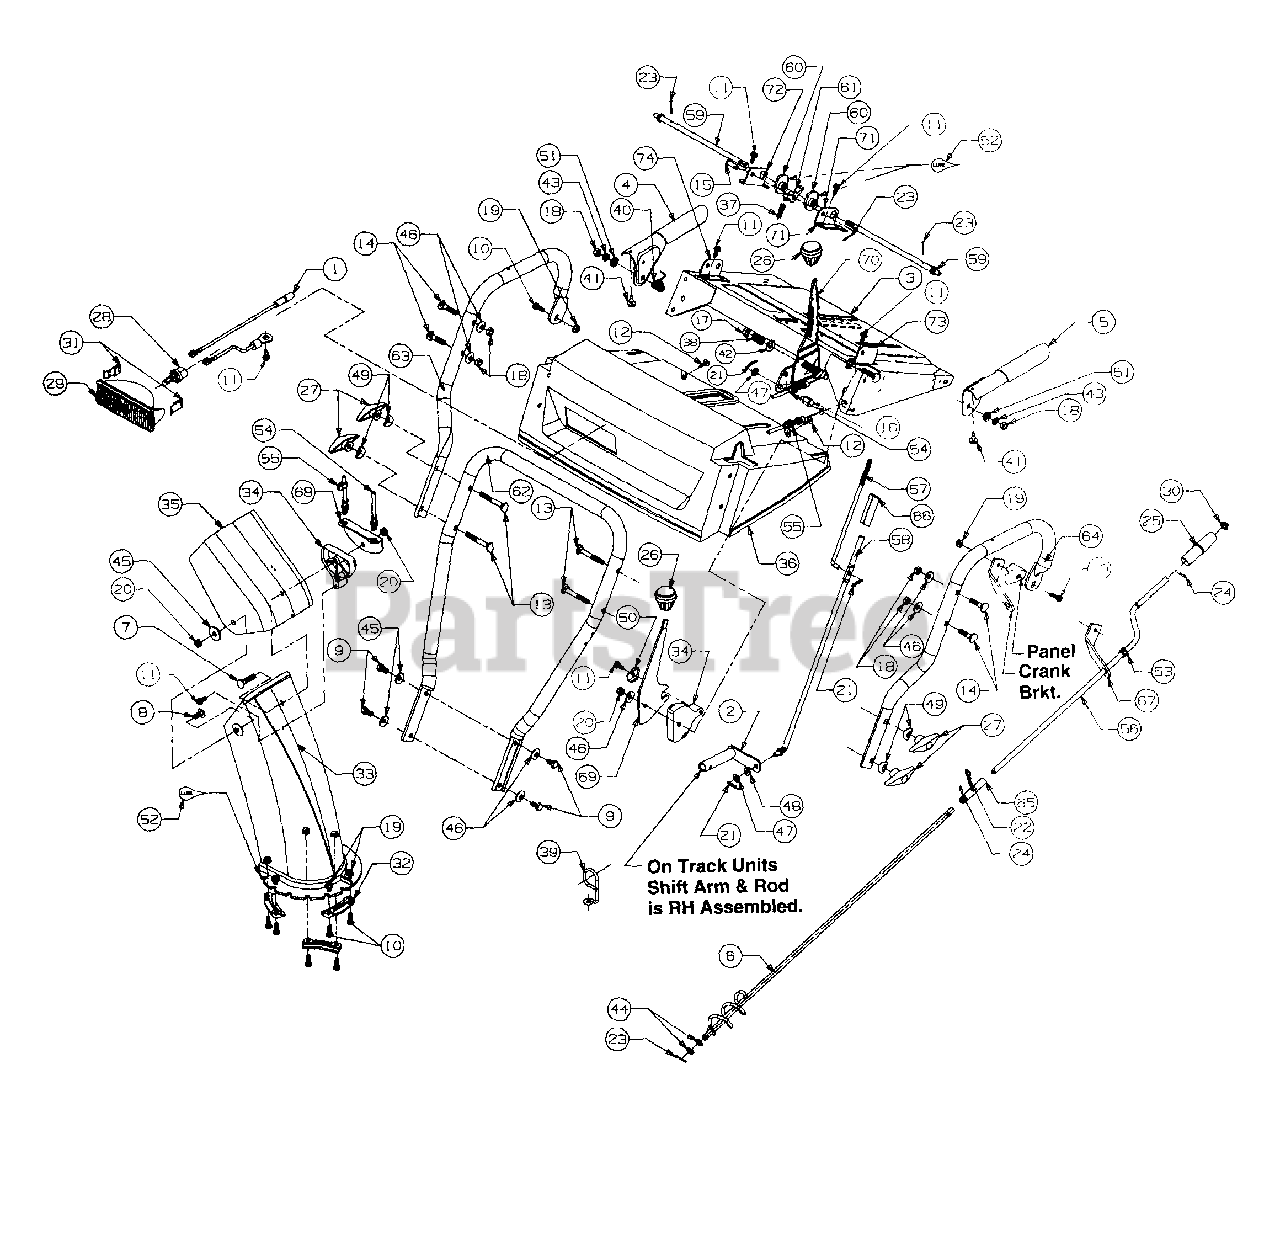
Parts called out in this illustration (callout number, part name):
1	Harness-Light
5	Handle-Engagement - L.H.
8	Bolt-Carriage
9	Screw-Hex
10	Screw-Hex
11	Screw-Washer Head-Hex
12	Screw-Hex
13	Bolt-Carriage
14	Bolt-Carriage
15	Pin-Clevis
16	Ferrule
17	Nut-Hex Lock
18	Nut-Hex
19	Nut-Hex Lock
20	Nut-Hex Lock
21	Pin-Cotter Internal
22	Pin-Cotter
23	Pin-Cotter
24	Pin-Roll
25	Knob-Chute Crank
26	Knob-Shift
27	Knob-Wing Nut
28	Lamp
29	Housing-Lamp
30	Cap Push
31	Clip-Retaining
32	Keeper-Chute
33	Chute-Lower
34	Guide-Cable
35	Chute-Upper
36	Panel Handle
37	Spring
38	Spring
39	Wire-Control
40	Spring
41	Bumper
42	Washer-Bell
43	Washer-Lock
44	Washer-Flat
45	Washer
46	Washer-Bell
47	Washer-Flat
48	Washer-Lock
49	Washer-Saddle
50	Washer
51	Washer
52	Lubricant
53	Bushing-Plastic
54	Cable-Chute Control
55	Cable-Chute Control
56	Crank-Chute
57	Rod-Shift Upper
58	Rod-Shift Lower
59	Rod-Cam
60	Cam-Handle Lock
61	Pawl-Handle Lock
66	Connector
70	Handle-Shift
